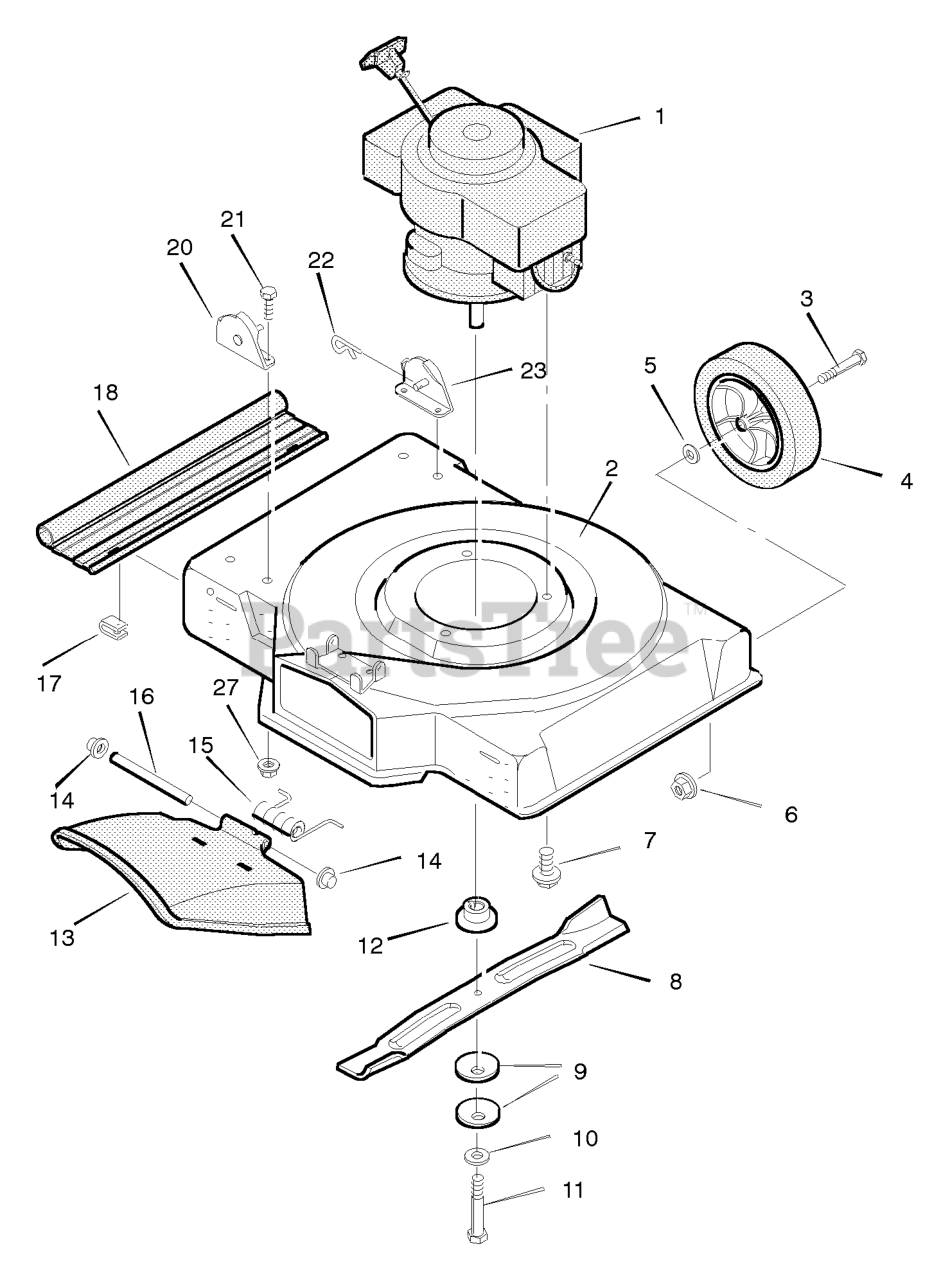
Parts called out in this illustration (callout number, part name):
1	Engine *
2	Housing
3	Bolt, Axle
4	Wheel and Tire *
6	Locknut, Flange
7	Bolt, Engine
9	Washer, Belleville
11	Bolt, Hex
12	Adapter, Blade
13	Deflector, Chute
14	Push- On Cap
16	Pin, Pivot
17	Retainer
18	Deflector, Rear
20	Bracket, Right Handle
22	Pin, Hair
23	Bracket, Left Handle
27	Nut
28	Hub Cap
29	Hub Cap
